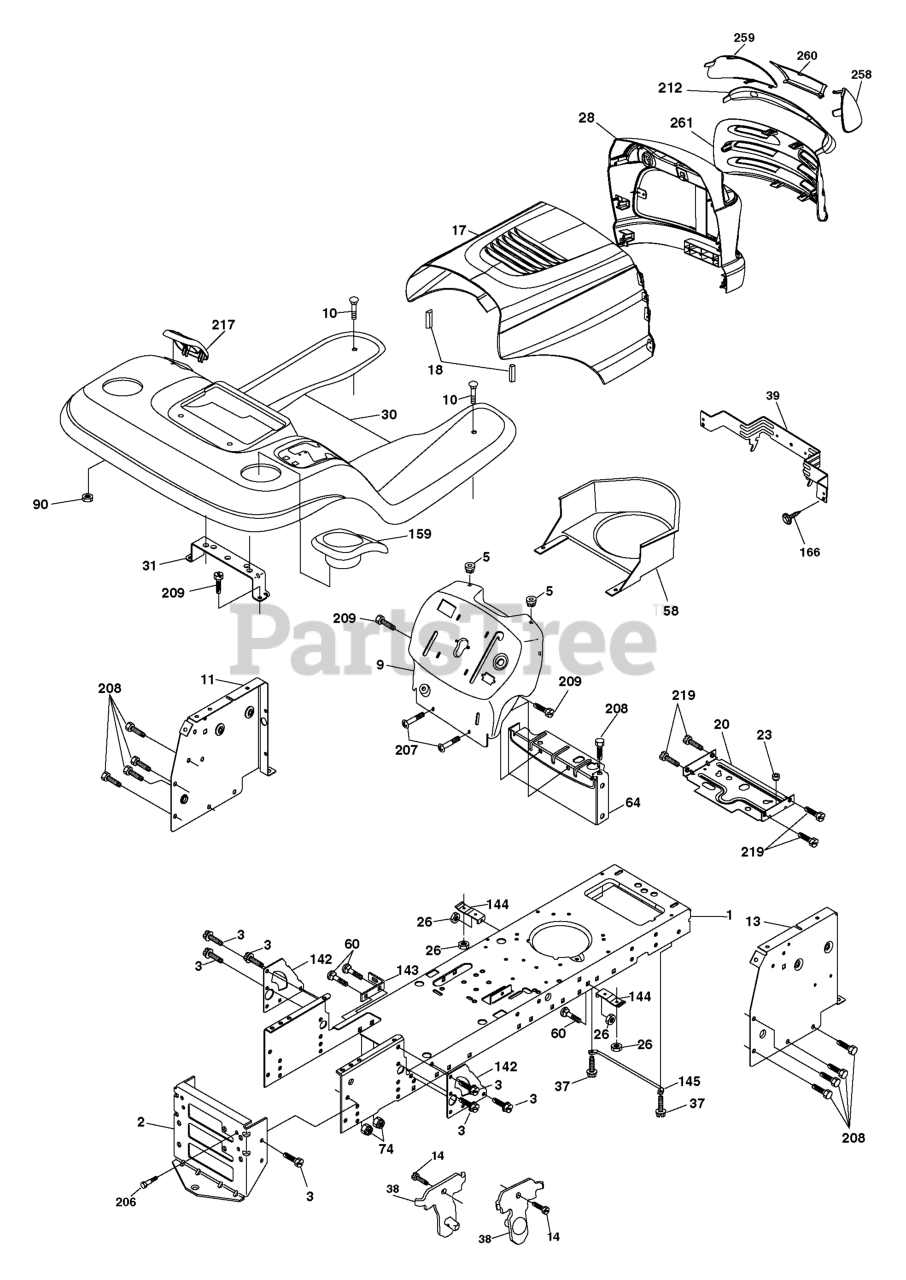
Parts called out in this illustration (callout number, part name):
1	CHASSIS STAMPING
2	DRAWBAR, 12GA
3	SCREW 3/8-16X3/4
5	BUMPER.RUBBER.HOOD
9	DASH(SUBS)
10	BOLT D
11	PANEL.DASH.LH.LTX
13	PANEL ASM, DASH RH
14	SCREW LT
17	HOOD
18	BUMPER.HOOD.LARGE.1.75"
20	PLATE MTG.BATTERY/FUEL TANK
23	BUSHING.SNAP.NYL.BLK.
26	NUT
28	GRILL/LEN.ASM.DL.HUSQ
30	FENDER
31	BRACKET.SUPPORT.FENDER
37	Screw Thdrol 5/16-18 x 1/2
38	BRACKET.ASM.PIVOT.MOWER.REAR
39	BRACKET PIVOT LASER
58	AIR DUCT
60	Bolt RDHD SQNK 3/8-16 x 3/4
64	DASH LOWER
90	NUT.PUSH.3/16
142	PLATE REINFORCEMENT
143	BRACKET, SWAY BAR
144	BRKT, FOOT REST
145	ROD PIVOT CHASSIS/HOOD
159	GREY CUP HOLDER
166	SCREW
206	SHOULDER BOLT 5/16-18TT
207	SCREW, 5/16-18 X 1/2
208	SCREW 3/8-16X1/2
209	SCREW, 3/8-16X3/4
212	INSERT.LENS.REFLECTIVE
217	CONSOLE FUEL WINDOW
219	SCREW
258	LENS LH
259	LENS LH
260	COVER.LENS.HUSQ.( HAVE GRAY)
261	INSERT GRILLE
